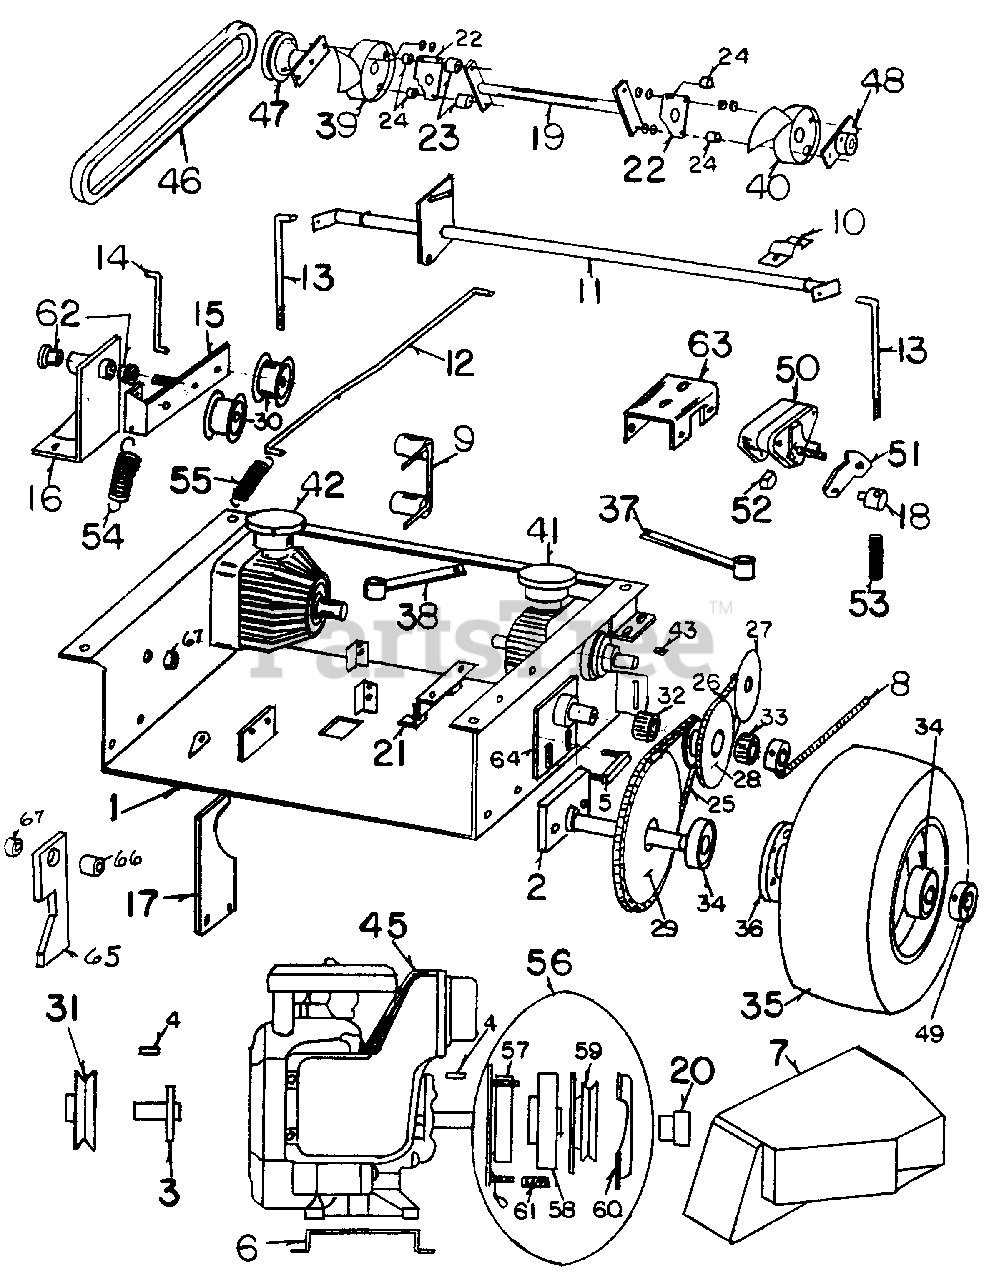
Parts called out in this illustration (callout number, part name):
1	BASE
2	AXLE, DRIVE WHEEL
4	KEY STOCK
6	11 H.P. ADAPTER PLATE
7	AIR DUCT
8	L.H. 1 R.H. SUPPORT COLLARS
10	BEARING, CLUTCH BRAKE CROSS ROD
11	CLUTCH BRAKE CROSS ROD
12	BRAKE PEDAL ROD
15	CLUTCH PULLEY MOUNT
16	CLUTCH BRACKET
17	BELT RETAINER, ENGINE
18	CALIPER OD COLLAR
20	ELECTRIC CLUTCH RETAINER
21	ELECTRIC CLUTCH STOP
22	DRIVE PLATE
25	CHAIN, FINAL DRIVE
26	CHAIN, PRIMARY DRIVE
27	SPROCKET TRANSMISSION DISC BRAKE
28	SPROCKET, PRIMARY DRIVE
29	SPROCKET, FINAL DRIVE
30	IDLER PULLEY
31	PULLEY, ENGINE
32	SHORT BEARING, IDLER SPROCKET
33	LONG BEARING, IDLER SPROCKET
34	BEARING, DRIVE WHEEL
35	DRIVE WHEEL ASSEMBLE
36	WHEEL HUB
37	ARM TRANSMISSION R.H.
38	ARM, TRANSMISSION L.H.
39	C.W. FAN R.H. SIDE
40	C.C.W. FAN L.H. SIDE
41	TRANSMISSION L.H. C.W.
42	TRANSMISSION R.H. C.C.W.
43	TRANSMISSION KEY
45	BRIGGS STRATTON 18 H.P.
46	BELT, TRANSMISSION
47	PULLEY,TRANSMISSION WITH DRIVE PLATE 3A:
48	HUB, TRANSMISSION WITH DRIVE PLATE 3AR
49	SET COLLAR, DRIVE WHEEL
50	BRAKE CALIPER
51	L.H. 1 EA CALIPER LEVER
53	CALIPER SPRING
55	BRAKE PEDAL SPRING
56	ELECTRIC CLUTCH
57	ELECTRIC CLUTCH COIL
58	ELECTRIC CLUTCH COIL HOUSING
59	CLUTCH ARMATURE
63	CALIPER BRACKET
64	SHAFT IDLER SPROCKET
65	FORWARD NOSE DOWN LOCK
66	BUSHING LONG
67	BUSHING SHORT
